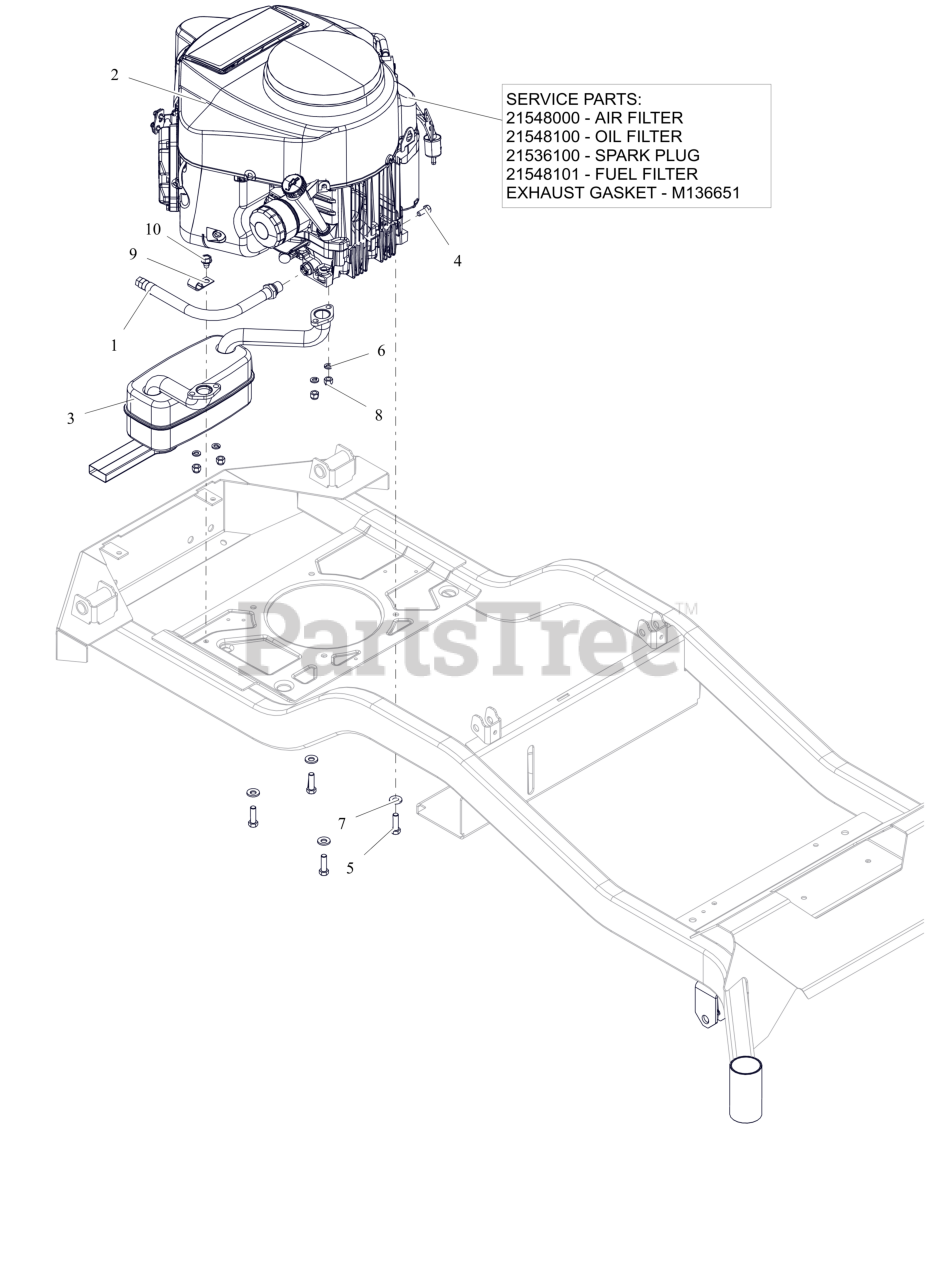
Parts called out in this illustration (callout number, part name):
1	HOSE, OIL DRAIN
2	ENGINE, KAWASAKI FR691 23HP
2	AIR FILTER, KAWASAKI FR
2	OIL FILTER, KAWASAKI FR
2	PLUG, SPARK
2	FUEL FILTER-KAWASAKI FR
2	GASKET, MUFFLER #
3	MUFFLER, KAWASAKI
4	BLT, HEX M8-1.25X20 G8.8 ZCC
5	BLT, HEX .38-16X1.25 G5 ZCC NT
6	WSHR,LK-REG .312X.078 ZCC
7	WASHER, 3/8" SPRING DISC
8	NUT, LK-CTR-JAM M8-1.25 GR8.8 ZC120
9	J-CLAMP
10	SCR,TAP .375-16X.50 HWH TR ZCC
